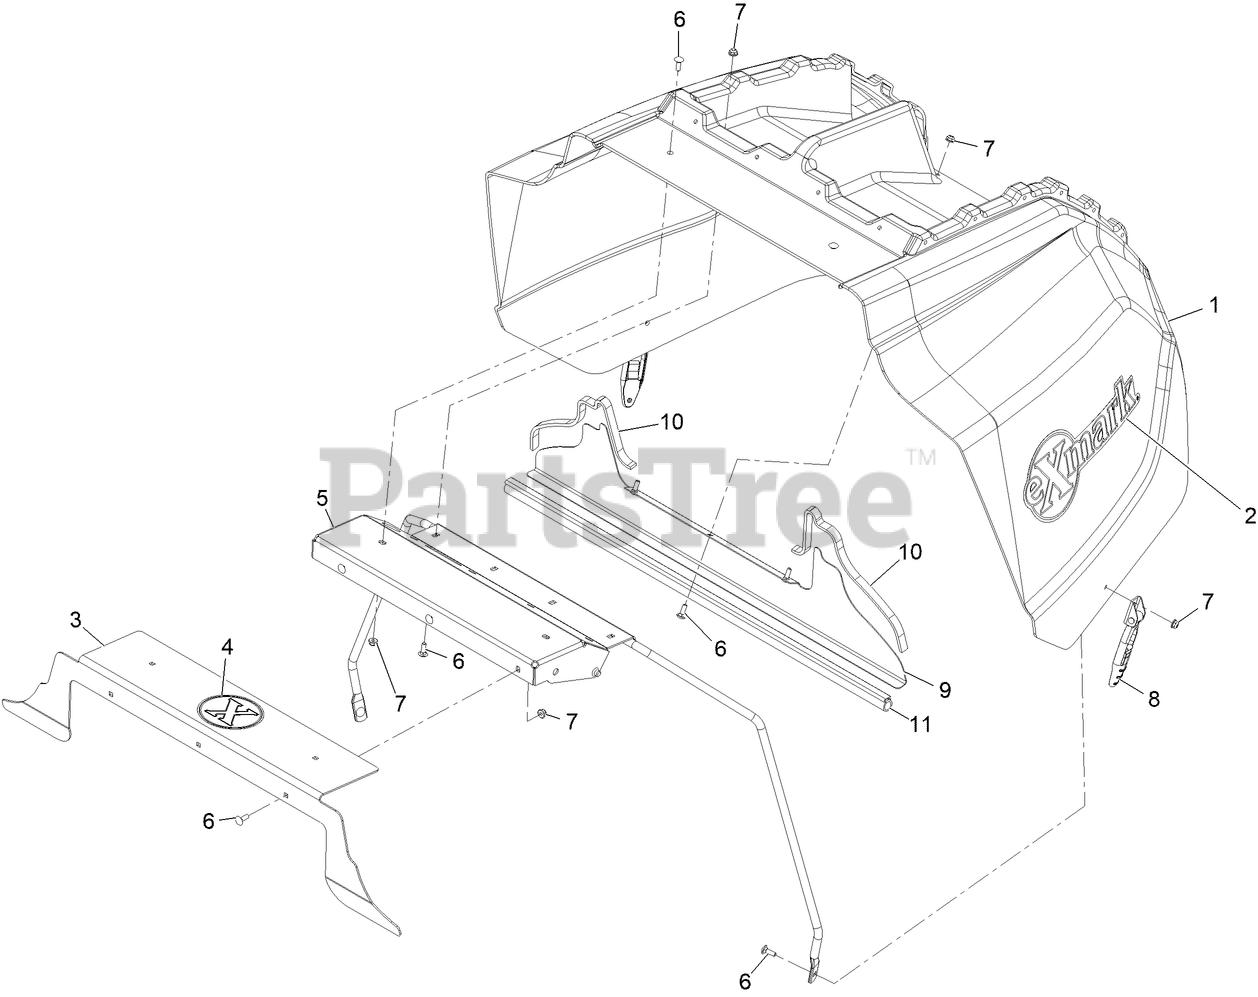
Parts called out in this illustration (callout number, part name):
1	HOOD,LZSD
2	DECAL-EXMARK
3	Block Off-Hood
4	DECAL-X-LOGO
5	SUPPORT-HOOD
6	BOLT-CARR
8	LATCH-RUBBER
9	Plate-Seal
10	SEAL-FOAM
11	Seal-Bulb
